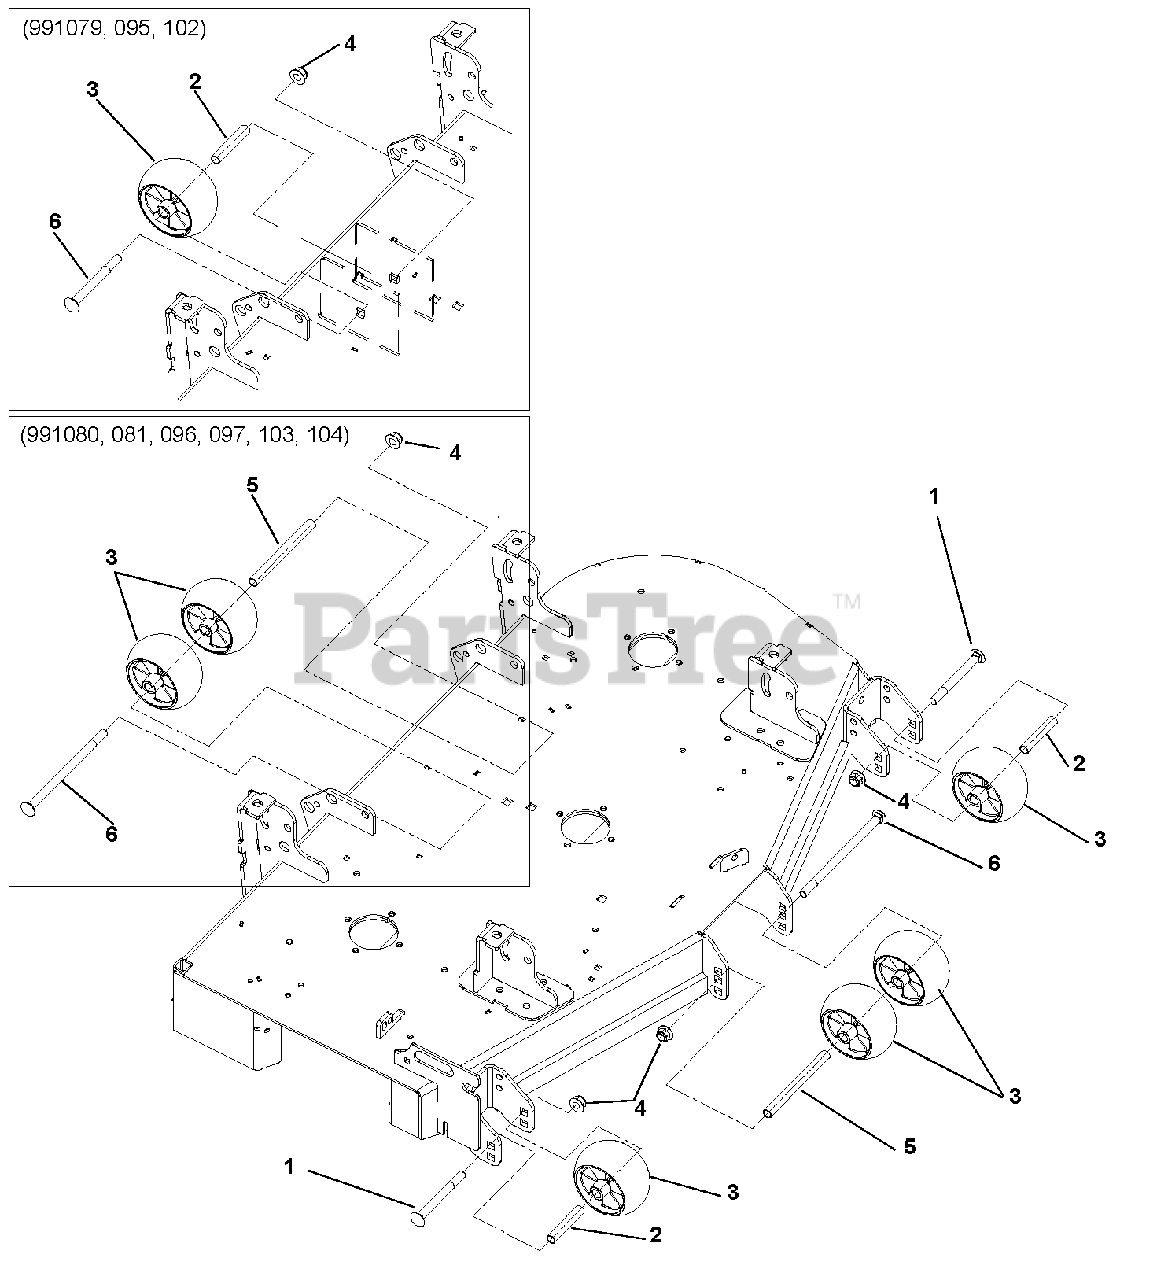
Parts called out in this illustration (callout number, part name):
1	Bolt, Round Head Square Neck .50-13 x 5.00 (991079, 095, 102)
2	Spacer, .510 x .625 x 3.35 (991079, 095, 102)
3	Anti-Scalp Wheel (991079, 095, 102)
4	Nut, Nyloc Flange .50-13
5	Spacer, .510 x .625 x 6.70 (991079, 095, 102)
6	Bolt, Round Head Square Neck .50-13 x 8.50 (991079, 095, 102)
